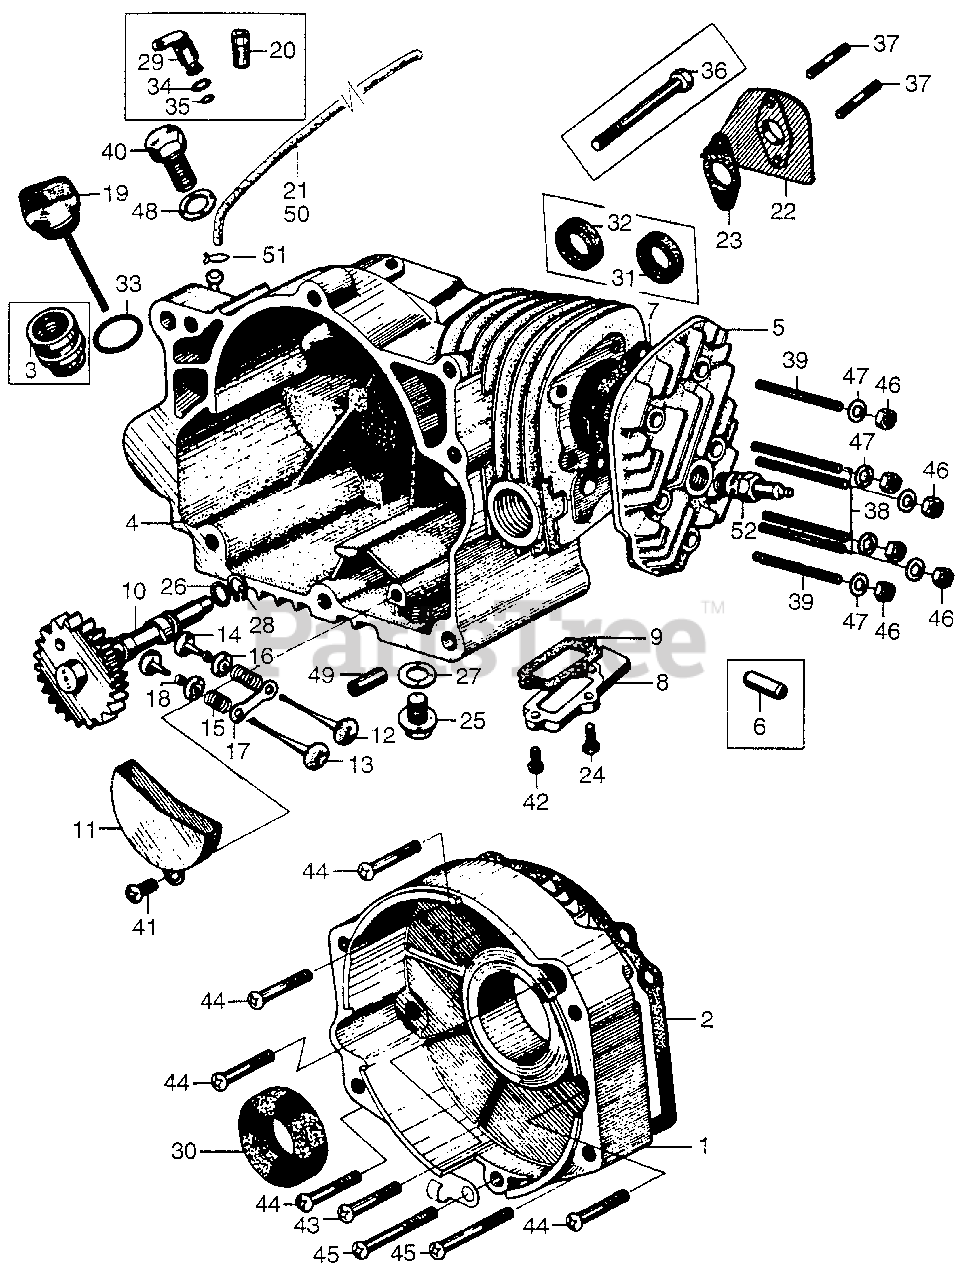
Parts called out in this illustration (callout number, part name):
1	COVER, CRANKCASE
2	GASKET, CASE (NOT AVAILABLE)
4	CYLINDER
5	CYLINDER HEAD
7	GASKET, CYLINDER HEAD
8	COVER, TAPPET
9	GASKET, TAPPET COVER (NOT AVAILABLE)
10	CAMSHAFT (NOT AVAILABLE)
11	PROTECTOR, GEAR
12	VALVE, IN. (NOT AVAILABLE)
13	VALVE, EX. (NOT AVAILABLE)
14	LIFTER, VALVE (NOT AVAILABLE)
15	SPRING, VALVE (NOT AVAILABLE)
16	RETAINER, VALVE SPRING (NOT AVAILABLE)
17	SEAT, SPRING (NOT AVAILABLE)
18	ADJUSTER C, TAPPET CLEARANCE (3.42-3.45) (NOT AVAILABLE)
18	ADJUSTER F, TAPPET CLEARANCE (3.33-3.36) (NOT AVAILABLE)
18	ADJUSTER, TAPPET CLEARANCE (3.24-3.27) (NOT AVAILABLE)
18	ADJUSTER, L. TAPPET CLEARANCE (3.15-3.18)
18	ADJUSTER, TAPPET CLEARANCE (3.06-3.09)
19	CAP, OIL (NOT AVAILABLE)
20	BREATHER (NOT AVAILABLE)
21	TUBE, BREATHER
22	INSULATOR, CARBURETOR
23	GASKET, CARBURETOR INSULATOR (NOT AVAILABLE)
24	BOLT, SPECIAL (5MM)
25	BOLT (10X12) (NOT AVAILABLE)
26	WASHER (18MM)
27	WASHER (10MM)
28	CIRCLIP (18MM)
29	PLUG, CYLINDER SEALING
30	OIL SEAL (20X40X6) (AJ-TYPE) (NOT AVAILABLE)
31	OIL SEAL (12X22X4) (AJ-TYPE) (NOT AVAILABLE)
31	OIL SEAL (18X28X5) (AJ-TYPE)
32	OIL SEAL (15X24X5)
33	O-RING (16MM)
33	O-RING (15.8X2.4) (SHOWA)
34	O-RING (9.8X1.9)
35	O-RING (8MM)
36	BOLT, HEX. (5X64) (NOT AVAILABLE)
37	BOLT, STUD (5X30)
38	BOLT 2, STUD (6X25)
38	BOLT, STUD (6X41) (NOT AVAILABLE)
39	BOLT, STUD (6X47)
39	BOLT, STUD (6X50)
42	SCREW, PAN (5X18)
44	SCREW, PAN (5X35)
47	WASHER, PLAIN (6MM)
49	PIN A, DOWEL (8X14)
52	SPARK PLUG (W20FP) (DENSO)
52	SPARK PLUG (W20FS-U) (DENSO)
52	SPARK PLUG (CM6) (NGK)
